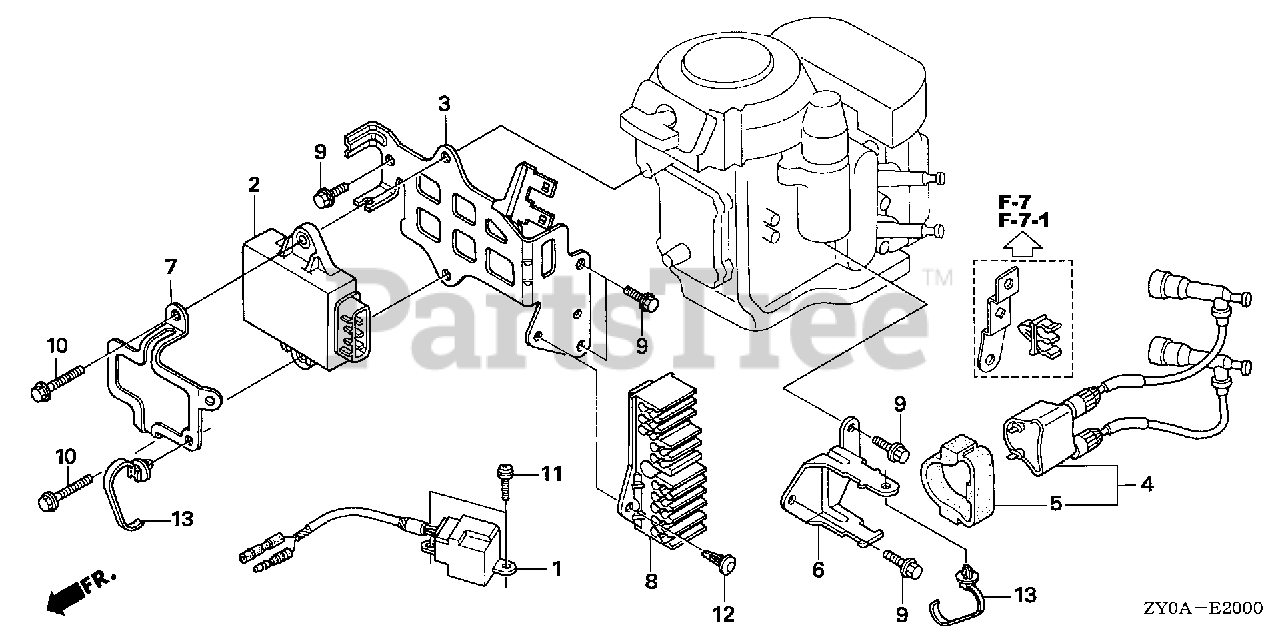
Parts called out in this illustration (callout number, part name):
1	COIL ASSY., PULSER
2	MODULE, IGNITION CONTROL (CDI)
3	PLATE, C.D.I.
4	COIL ASSY., IGNITION
5	SUSPENSION, IGNITION COIL
6	BRACKET, IGNITION COIL
7	BRACKET, C.D.I.
8	BRACKET, CONNECTOR
9	BOLT, FLANGE (6X14) (CT200)
10	BOLT, FLANGE (6X25)
11	SCREW-WASHER (5X16)
12	CLIP, ANCHOR
13	CLIP, HARNESS BAND (151.5MM) (NATURAL)
